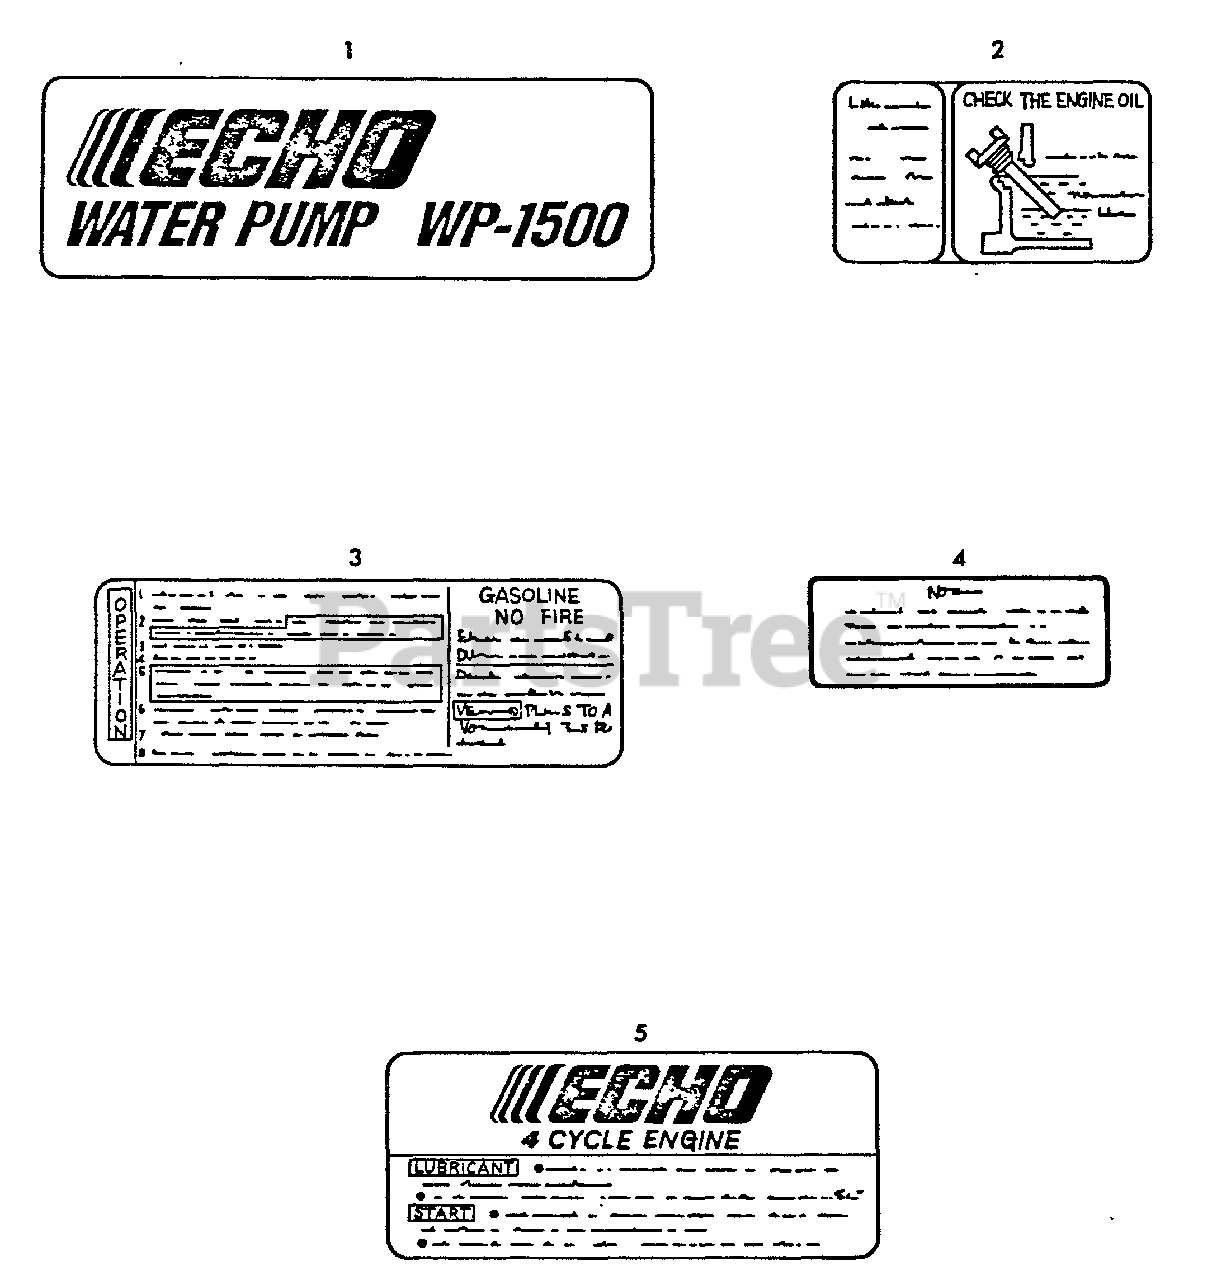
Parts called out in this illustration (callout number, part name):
1	LABEL - MODEL WP1500
2	LABEL - OIL
3	LABEL - OPERATION
4	LABEL - AIR CLEANER
5	LABEL - ECHO
